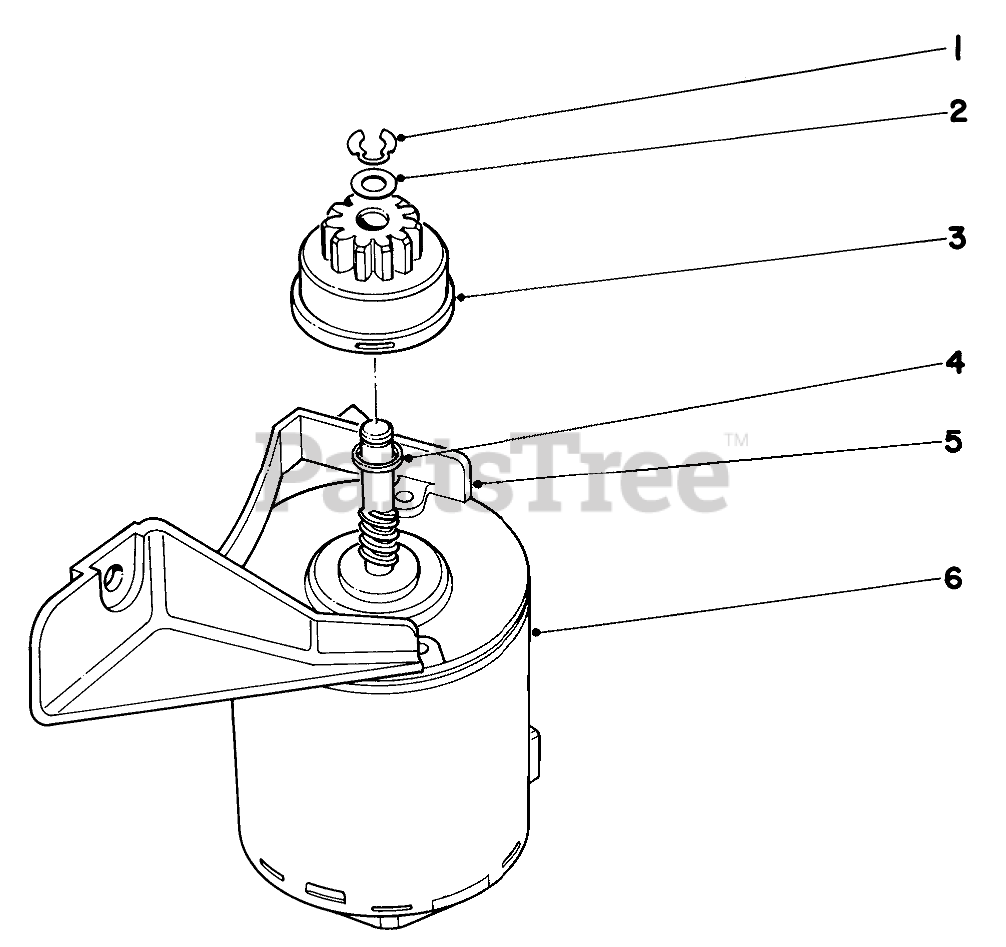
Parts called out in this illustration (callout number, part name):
1	RING-RETAINING
2	WASHER
3	PINION ASM
4	Spacer
5	Mounting Bracket
6	Starter Motor
